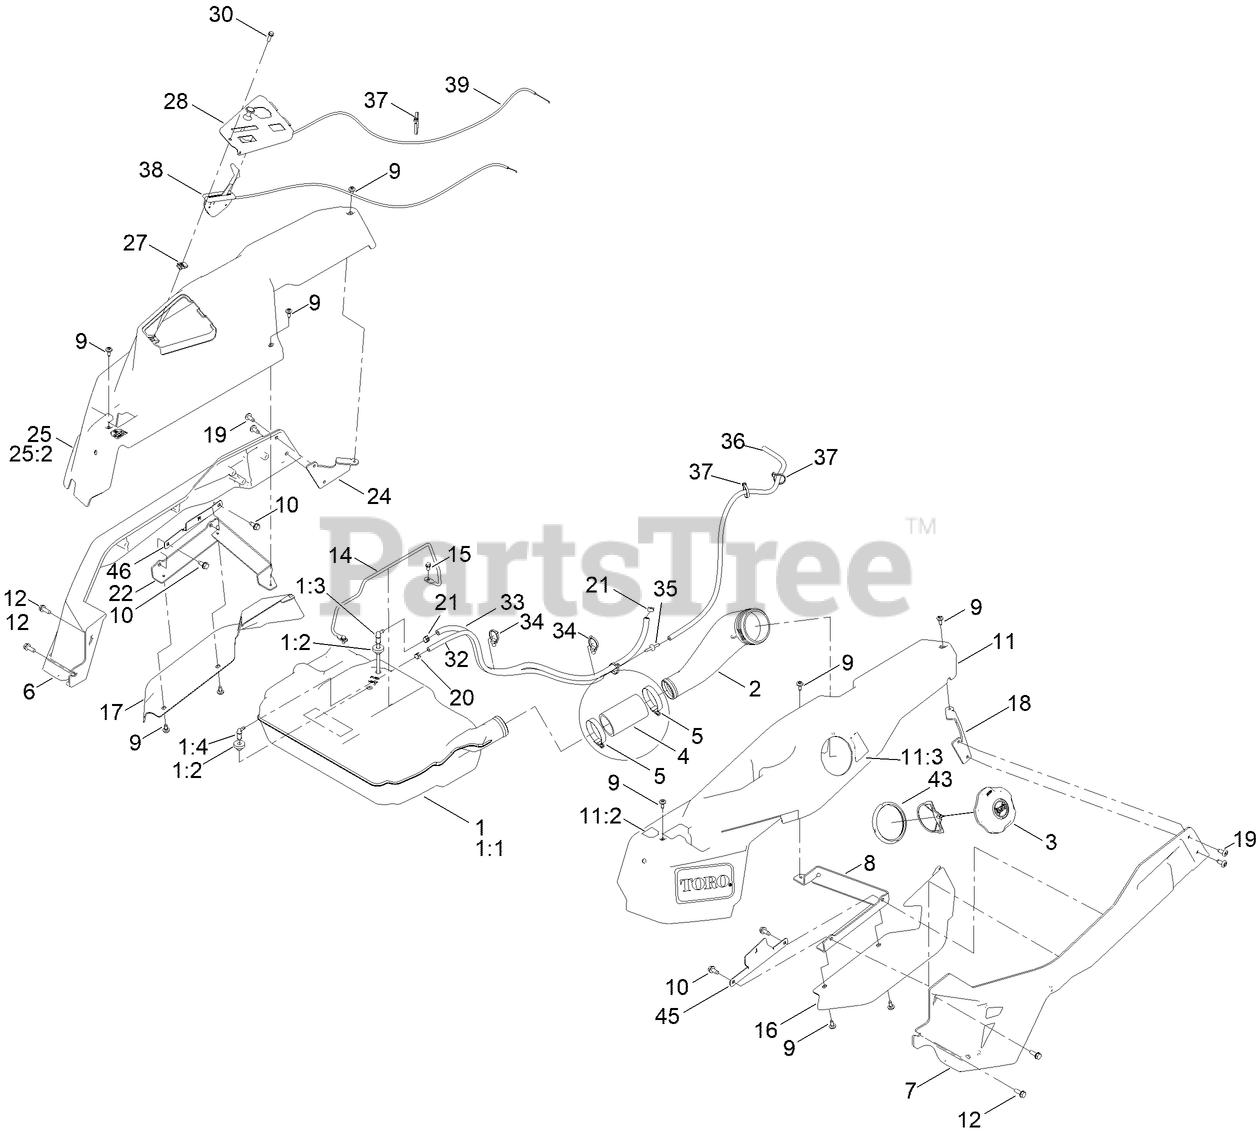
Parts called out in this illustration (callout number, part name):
1	TANK-FUEL ASM
1:1	TANK-FUEL
1:2	BUSHING
1:3	FITTING-ELBOW 90
1:4	FITTING - PICKUP, FUEL
2	NECK-FILLER, FUEL
3	CAP-FUEL, RATCHETING
4	HOSE-FILLER, FUEL
5	CLAMP-HOSE
6	CAST-TUBE, RH [BLK-TXT]
7	CAST-TUBE, LH [BLK-TXT]
8	MOUNT-POD BRACKET LH
9	SCREW-SHOULDER
10	SCREW-HWHTF
11	POD ASM - LH W/DECALS
11:2	DECAL-CONTROL LEVER, LH
11:3	DECAL-FUEL FILL
12	SCREW-TAPTITE
14	ROD-HOLD DOWN
15	SCREW-HWH
16	FENDER-TIME CUTTER, LH
17	FENDER-TIME CUTTER, RH
18	BRACKET-REAR POD, LH
20	CLAMP-HOSE
21	CLAMP-HOSE
22	MOUNT-POD BRACKET RH
24	MOUNT-POD BRACKET RH
25	POD ASM - RH W/DECALS
25:2	DECAL-CONTROL LEVER, RH
28	PANEL-CONTROL
30	SCREW-HWH
32	HOSE-FUEL
33	HOSE-FUEL
34	CLIP-TIE
35	ADAPTER ORIFICE
36	HOSE-LP
37	TIE-CABLE
38	CABLE-THROTTLE
39	CABLE-CHOKE
43	RING-RETAINING
45	BRACKET-ALIGNMENT, POD LH
46	BRACKET- ALIGNMENT, POD RH
